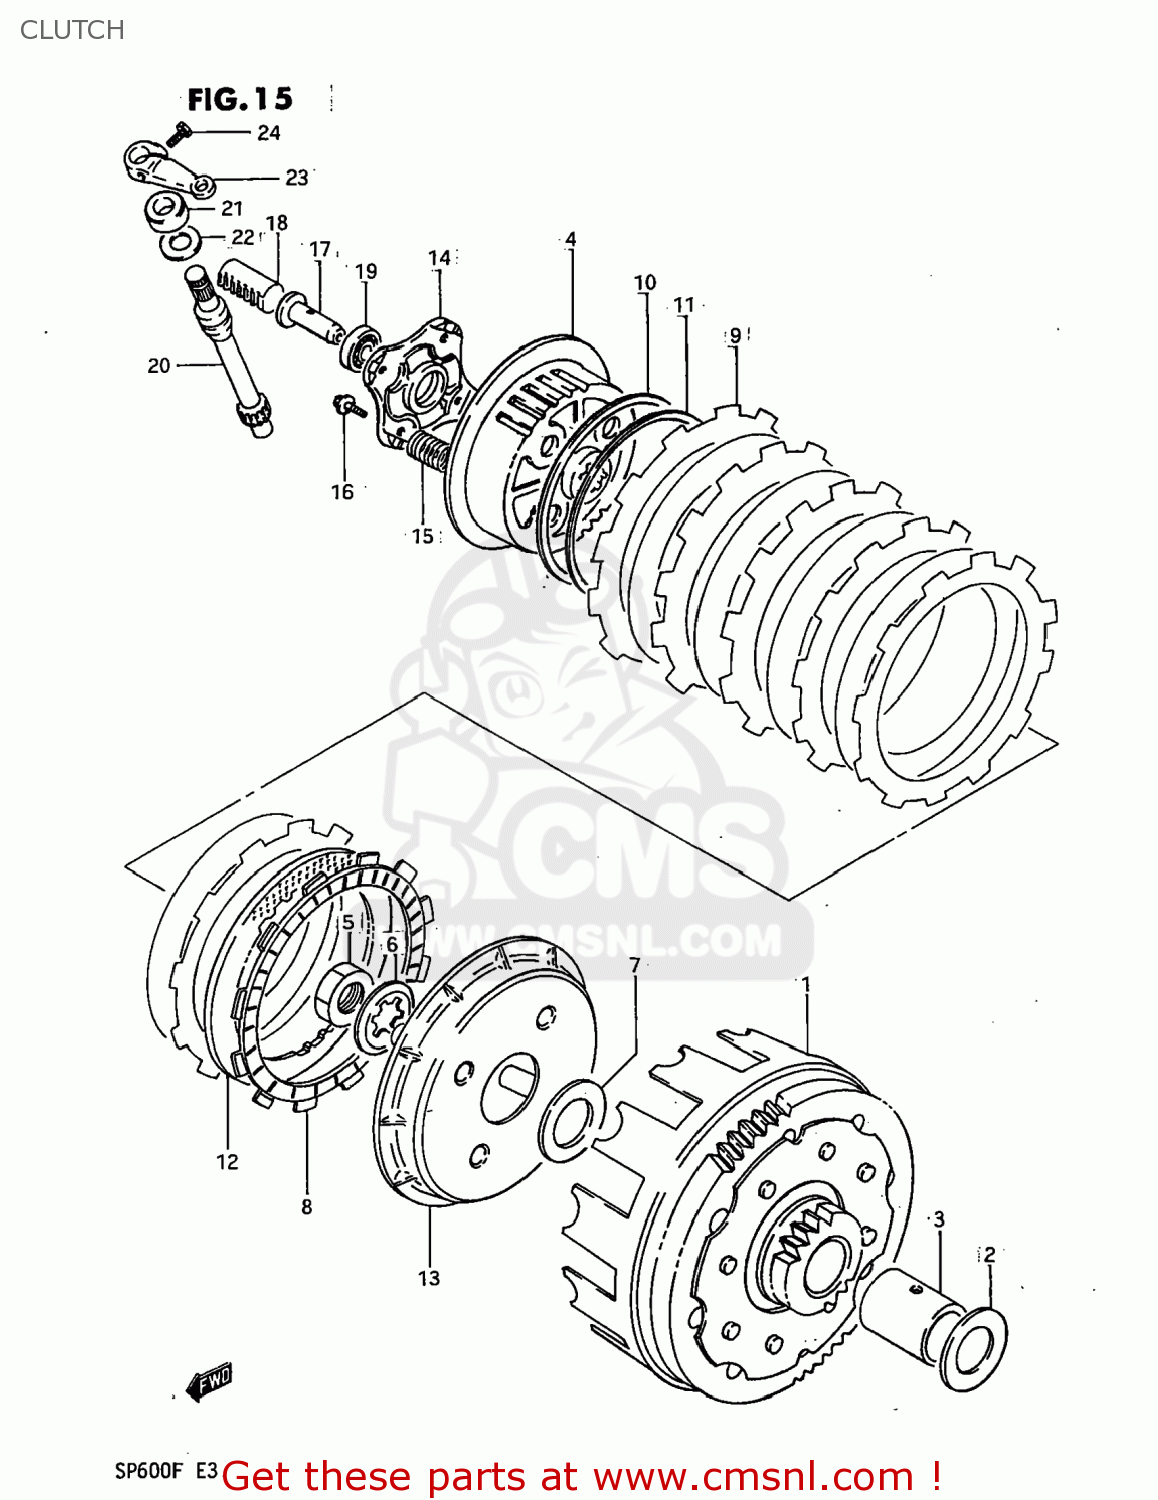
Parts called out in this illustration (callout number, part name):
1	GEAR ASSEMBLY,PRIMARY DRIVE
2	WASHER
3	SPACER(22X28X32.5)
4	HUB,CLUTCH SLEEVE
5	NUT
6	WASHER,LOCK
7	WASHER
8	PLATE,CLUTCH DRIVE (NAS)
9	PLATE,CLUTCH DRIVE
10	SEAT,WAVE WASHER(T:1.4)
11	WASHER
12	PLATE,CLUTCH DRIVEN(T:1.6) (NAS)
13	DISC,CLUTCH PRESSURE
14	PLATE,RELEASE
15	SPRING
16	BOLT,REAR
17	PIECE,CLUTCH PUSH
18	RACK,CLUTCH RELEASE
19	BEARING
20	PINION,CLUTCH RELEASE
21	SEAL,OIL (12X22X9)
22	WASHER (14.2X22X1)
23	ARM,CLUTCH RELEASE
24	BOLT
